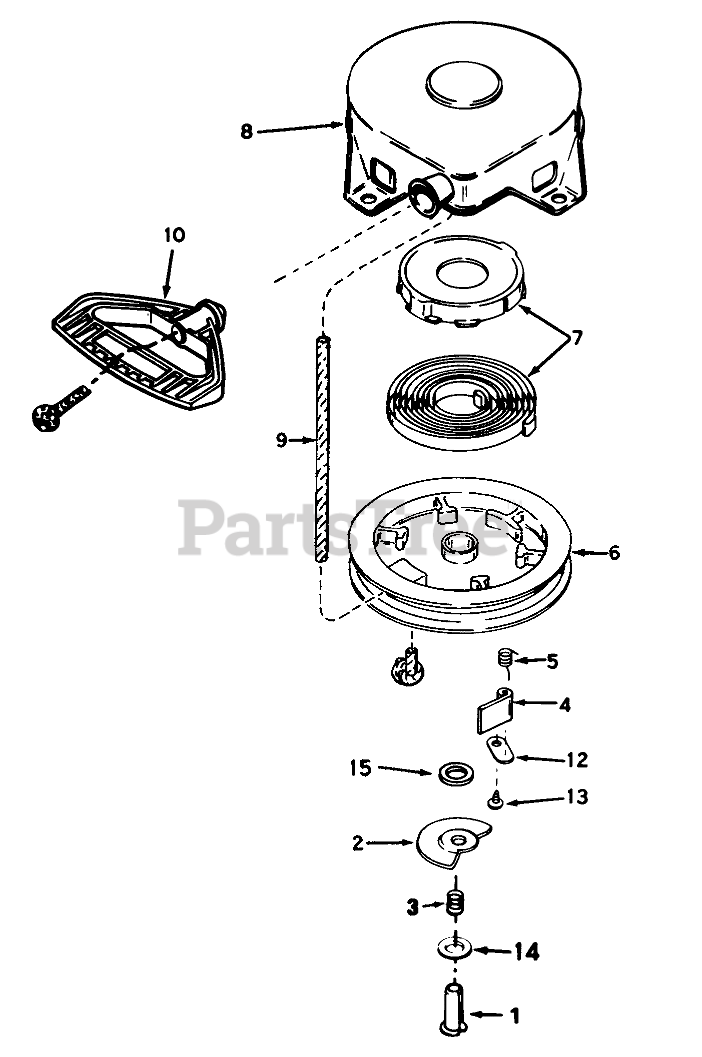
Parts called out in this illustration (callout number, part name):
1	Pin-Spring (Incl. Ref. #15)
3	Brake Spring
4	Dog-Starter
5	Spring-Dog
7	Spring & Keeper Assy
8	Housing-Starter
9	Rope-Starter
10	Handle-Starter, Mitten Grip
12	Retainer-Dog
